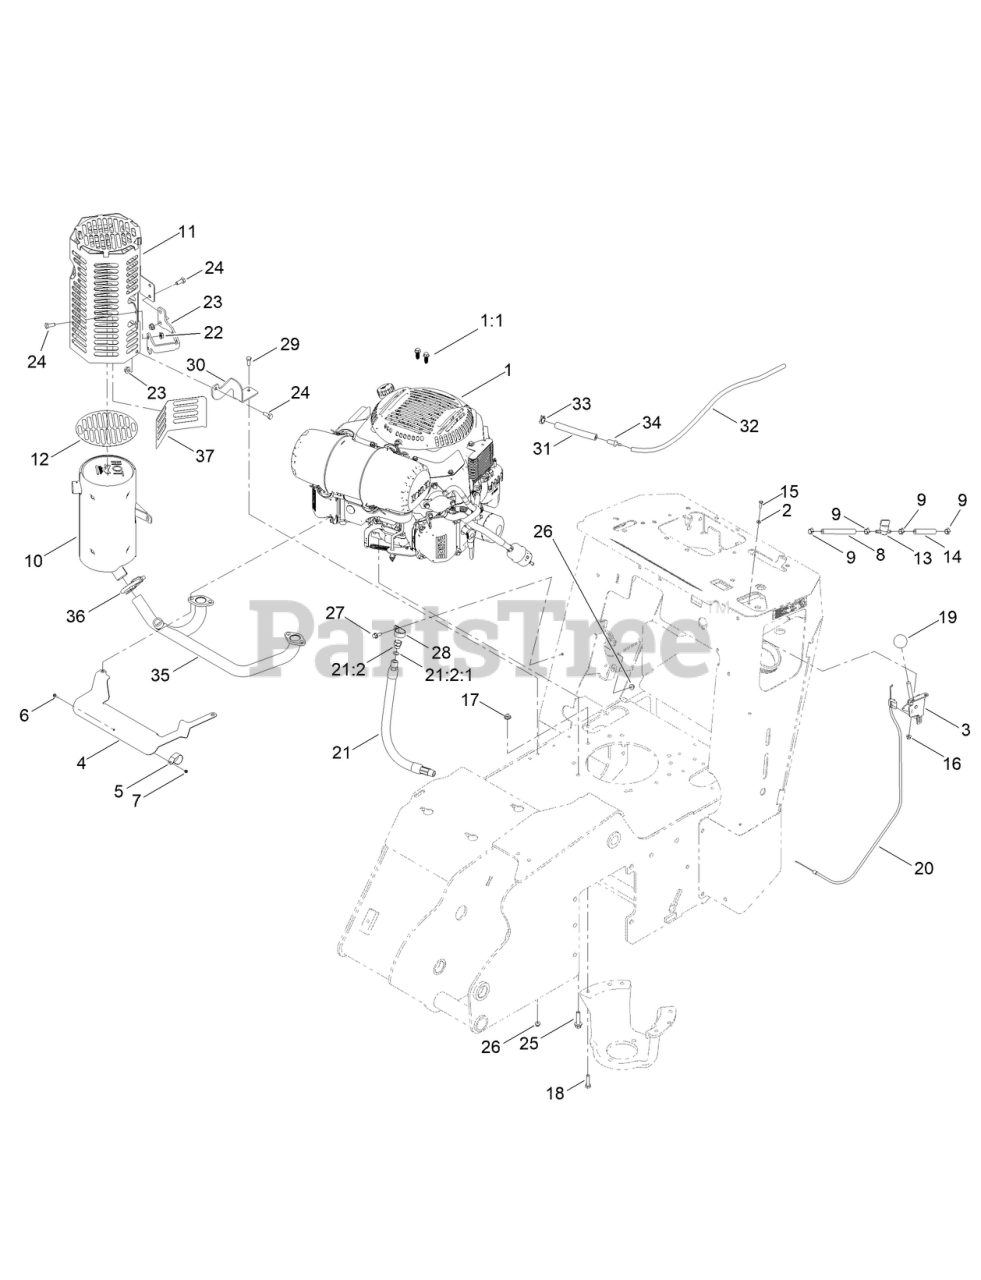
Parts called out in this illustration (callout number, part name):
1	ENGINE-KOHLER, PS-ECV749-3068
1:1	SCREW-HI-LOW, KOHLER
2	WASHER-FLAT
3	LEVER-CONTROL
4	SHIELD-HEAT
6	SCREW-PAN
7	NUT-HEX
8	HOSE-FUEL
9	CLAMP-HOSE
10	MUFFLER-KOHLER
11	GUARD-MUFFLER
12	FOIL-GUARD
13	VALVE-FUEL
14	HOSE-FUEL
16	NUT-HF
17	NUT-HF
18	SCREW-HH
20	CABLE-CONTROL
21	OIL DRAIN HOSE ASM
21:2	PLUG-HH
21:2:1	O-RING
22	BRACKET-MUFFLER
23	NUT-FLANGE
24	SCREW-HH
25	SCREW-HWH
26	NUT-HF
27	SCREW-HHF
28	CLAMP-R
29	SCREW-HH
30	BRACKET-GUARD, MUFFLER
31	HOSE-VENT
32	HOSE-VENT
33	CLAMP-HOSE
34	FITTING-ORIFICE, STRAIGHT
35	MANIFOLD-KOHLER
36	CLAMP-MUFFLER
37	GUARD-FOIL
